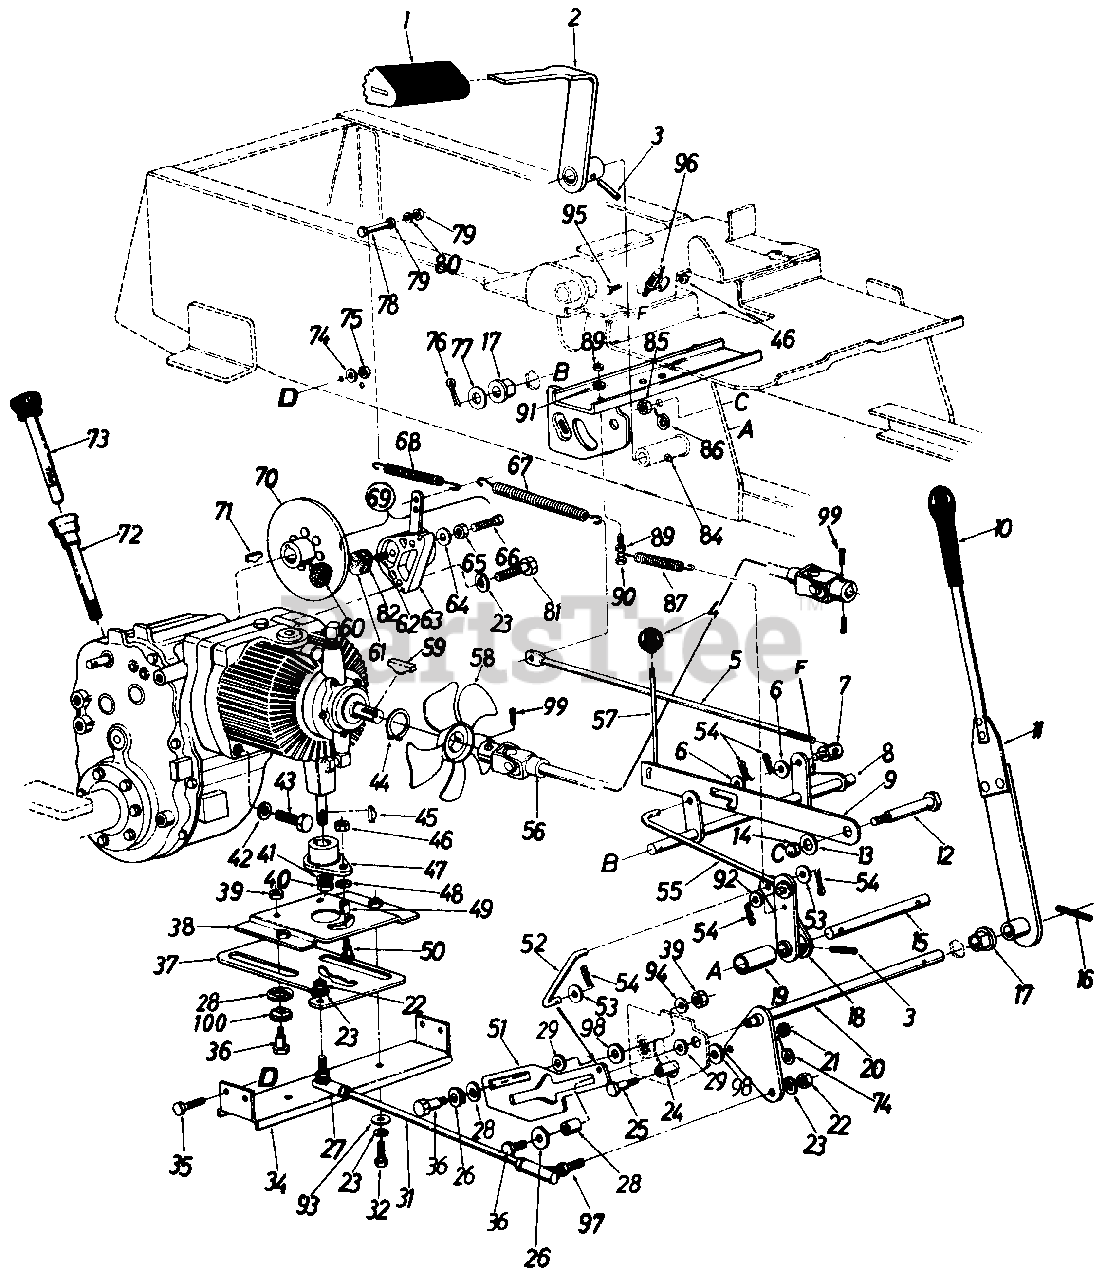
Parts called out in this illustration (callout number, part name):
1	Foot Pad
4	Ball Knob - Brake
5	Brake Rod
6	Fl-Wash. .375" I.D. x 1.00" O.D. x .030"
7	Ferrule
8	Brake Transfer Shaft Ass'y.
9	Parking Brake Cam
11	Control Arm Ass'y. Comp.
12	Shld. Bolt .62" Dia. x 2.75" Lg.
13	Fl-Wash. .460" I.D. x 1.24" O.D. x .06"
14	Push Speed Nut for .625" Dia. shaft
15	Brake Pivot shaft
16	Spring Pin Spiral 1/4" Dia. x 1.50" Lg.
17	Hex Flange Brg. Plastic .62" I.D.
18	Brake Lever Ass'y.
19	Spacer
20	Control Handle Shaft Ass'y.
21	Hex Cent. L-Nut 5/16-18 Thd.
22	Hex Nut 3/8-24 Thd.
23	L-Wash. 3/8" I.D.
24	Spacer
25	Shoulder Bolt
26	Fl-Wash. 7/16" I.D. x 1-3/8" O.D.
27	Ball Joint Ass'y. 3/8-24 Thd.-L.H.
28	Spacer
29	Fl-Wash. .325" I.D. x 1.25" O.D.
31	Tie Rod
32	Hex Bolt 3/8-16 x .75" Lg.
34	Support Channel
35	Hex Bolt 5/16-18 x .75" Lg.
36	Shld. Bolt .437" Dia. x .268"
37	Cam Plate
38	Slide Mtg. Plate Ass'y.
39	Hex Cent. L-Nut 5/16-18 Thd.
40	Hex Nut 1/2-13 Thd.
41	L-Wash. 1/2" I.D.
42	Fl-Wash. .385" I.D. x .87" O.D. x .060"
43	Socket Hd. Scr. 3/8-16 x 2.75" Lg.
44	Snap Ring
45	#5 Hi-Pro Key 1/8" x 5/8" Dia.
46	Hex Cent. L-Nut 1/4-20 Thd.
47	Pintle Plate Ass'y.
48	Fl-Wash. .281" I.D. x .50" O.D. x .063"
49	Needle Brg. .31" I.D. x .50" O.D. x .437" Lg.
50	Shld. Bolt .31" Dia. x .500
51	Neutral Control Slide
52	Neutral Control Rod
53	Fl-Wash. .312" I.D. x .630" O.D. x .063"
54	Hairpin Cotter
55	Brake Link Rod Ass'y.
56	Universal Drive Shaft Comp.
57	Parking Brake Link
58	Fan Ass'y.
59	#61 Hi-Pro Key 3/16 x 5/8" Dia.
60	Lining - Brake
61	Lining - Brake
62	Actuator Pin
63	Housing with Lever and Pin
65	Nut
66	Adjustment Pin
67	Extension Spring .50" O.D. x 6.5" Lg.
68	Extension Spring (Brake Return)
69	Disc Brake Ass'y. Comp.
70	Brake Disc Ass'y.
71	Hi-Pro Key 3/16 x 3/4" Dia.
72	Dipstick Tube Ass'y.
73	Dipstick Ass'y.
74	L-Wash. 5/16" I.D.
75	Hex Nut 5/16-18 Thd.
76	Cotter Pin 1/8" Dia. x 1.00" Lg.
77	Fl-Wash. .635" I.D. x 1.00" O.D. x .120" Thk.
78	Hex Scr. 1/4-20 x 2.50" Lg.
79	Hex Nut 1/4-20 Thd.
80	L-Wash. 1/4" I.D.
81	Hex Scr. 3/8-16 x 1.25" Lg.
82	Backing plate
84	Grease Fitting
85	Hex Nut 7/16-20 Thd.
86	L-Wash. 7/16" I.D.
87	Extension Spring
89	Hex Nut 1/4-20 Thd.
90	Hex Bolt 1/4-20 x 1.25" Lg.
91	L-Wash. 1/4" I.D.
92	Fl-Wash.
93	Fl-Wash. .38" I.D. x 1.25" O.D.
94	Bell-Wash.
95	Hex Bolt 1/4-20 x 1/2" Lg.
96	Safety Switch
97	Ball Joint Ass'y. 3/8-24 Thd. - R.H.
98	Fl-Wash. .32" I.D. x .6" O.D.
99	Set Screw 5/16-18 x .38" Lg.
100	Thrust Washer
